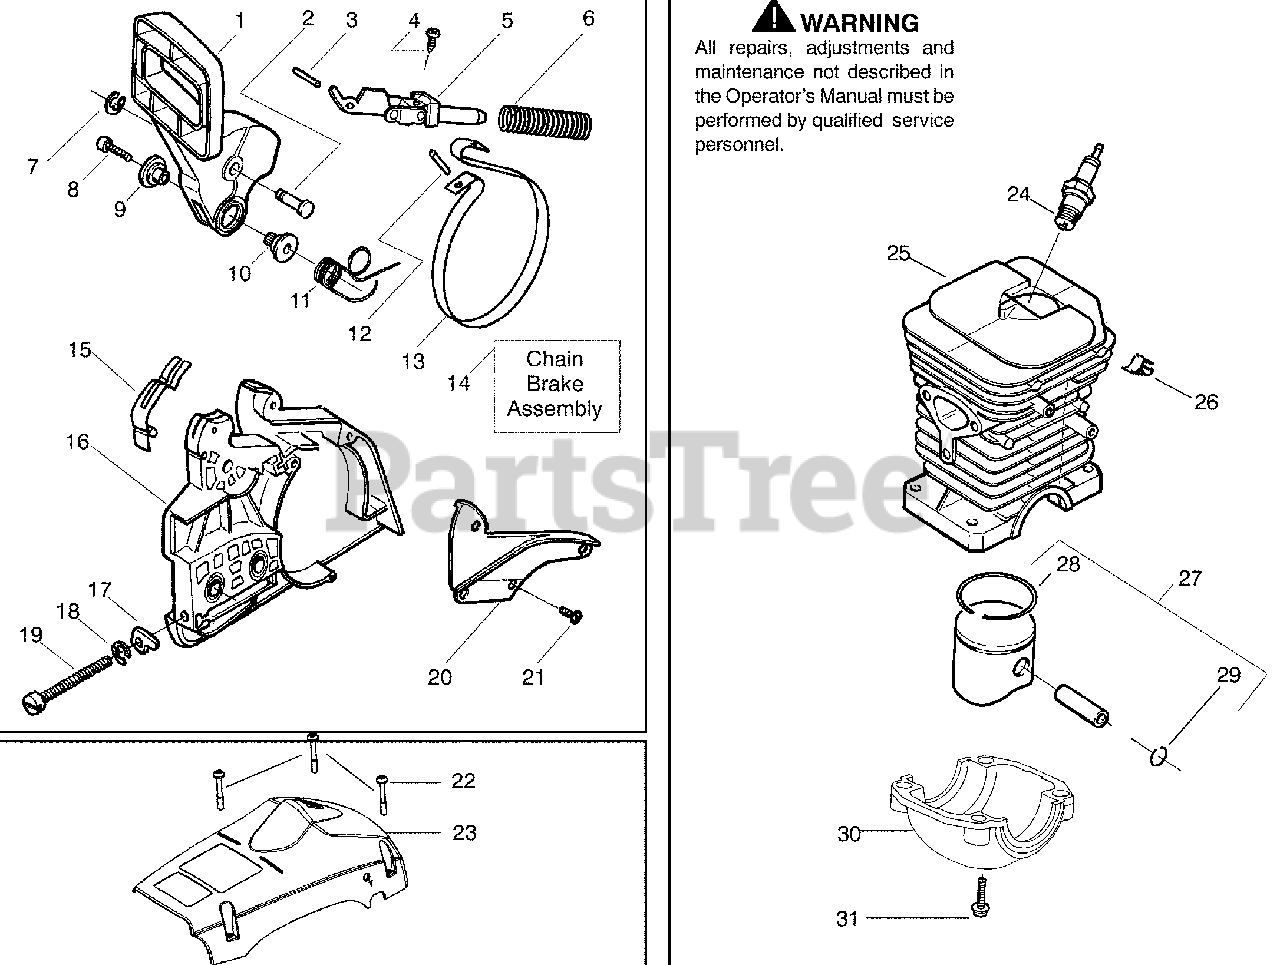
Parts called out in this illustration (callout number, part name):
1	Kit-- Lever & Link Assy. (Incl. 5,13)
2	Pin--Pivot
4	Screw
5	Assy--Front Link
6	Spring--Chain Brake
9	Journal--Right
10	Journal--Left
11	Spring--Handguard
12	Pin--Spring
13	Band--Brake
14	Assy--Chain Brake
15	Spring--Position
16	Cover--Clutch
17	Pin--Bar Adjusting
19	Screw--Bar Adjusting
20	Cover--Chain Brake Spring
21	Screw
23	Shield--Cylinder
24	Spark Plug (RCJ--7Y)
25	Kit--Cylinder (36cc) (incl.#29 pg. 1 & #23 pg. 2)
26	Clip -- High Tension Lead
27	Kit--Piston (36cc) (Includes pin and 28, 29)
28	Ring--Piston (36cc)
29	Piston Pin Retainer
30	Cap--Crankcase
